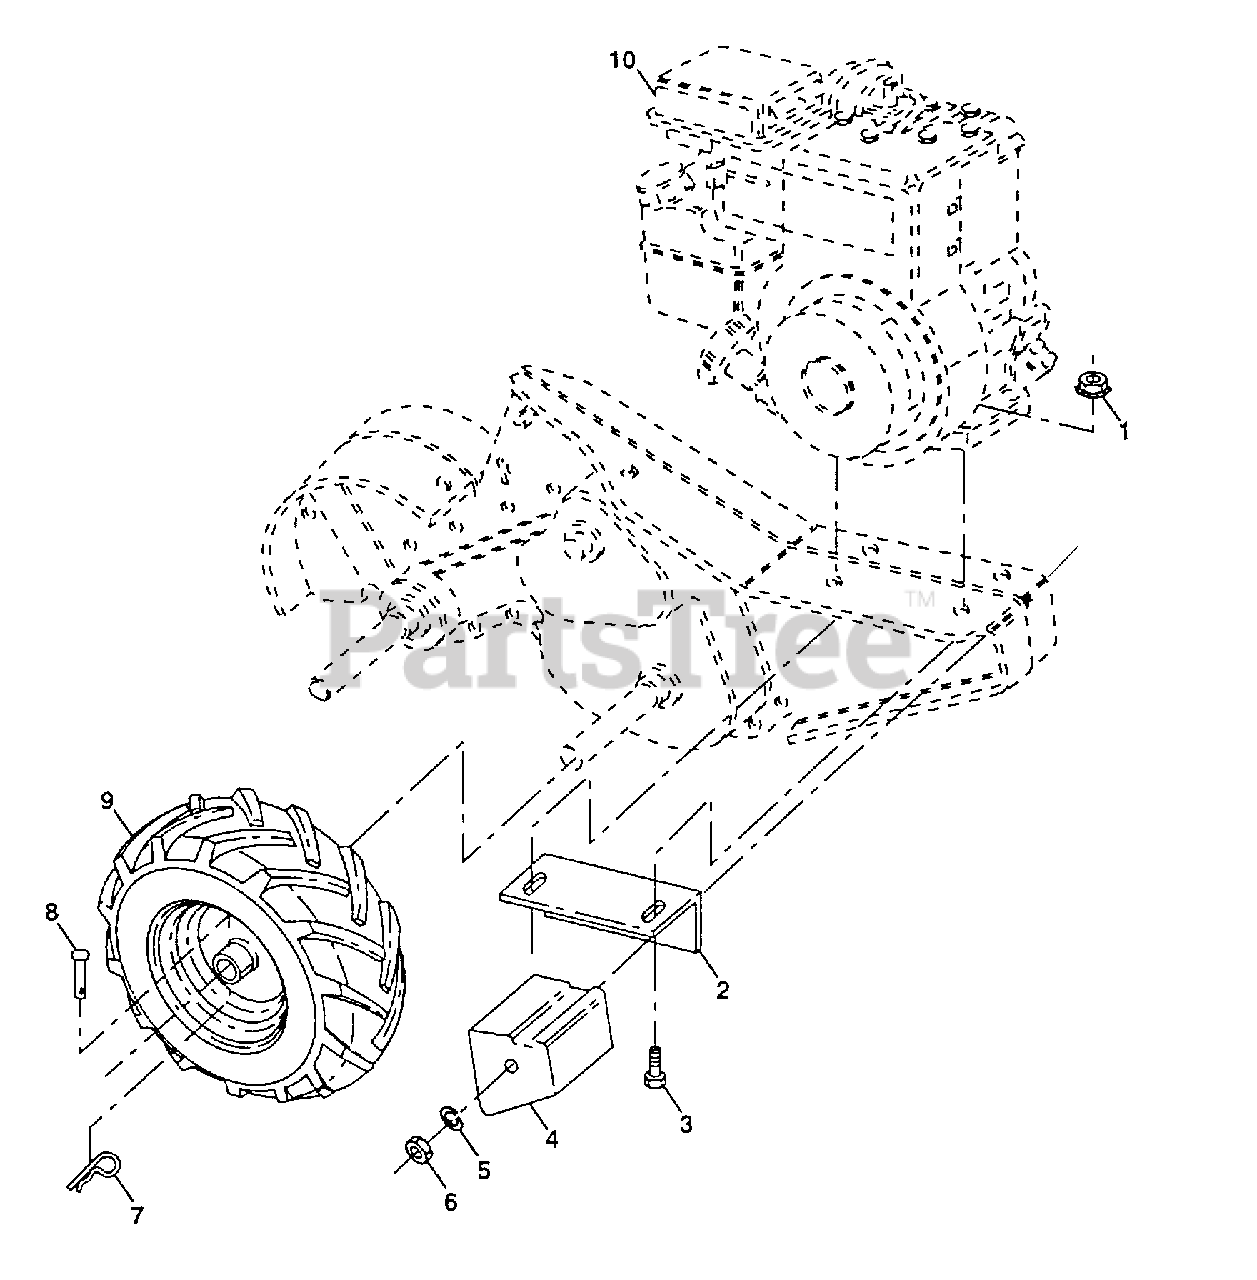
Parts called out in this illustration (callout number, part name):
2	BRACKET RH CRT
3	BOLT.HEX.5/16-1.5
4	COUNTERWEIGHT CRT
5	LOCKWASHER
6	NUT.HEX.3/8-16UNC
7	RETAINER M
8	RIVET.DRILL.1.75
9	TIRE.CHV.13X5.0-6
